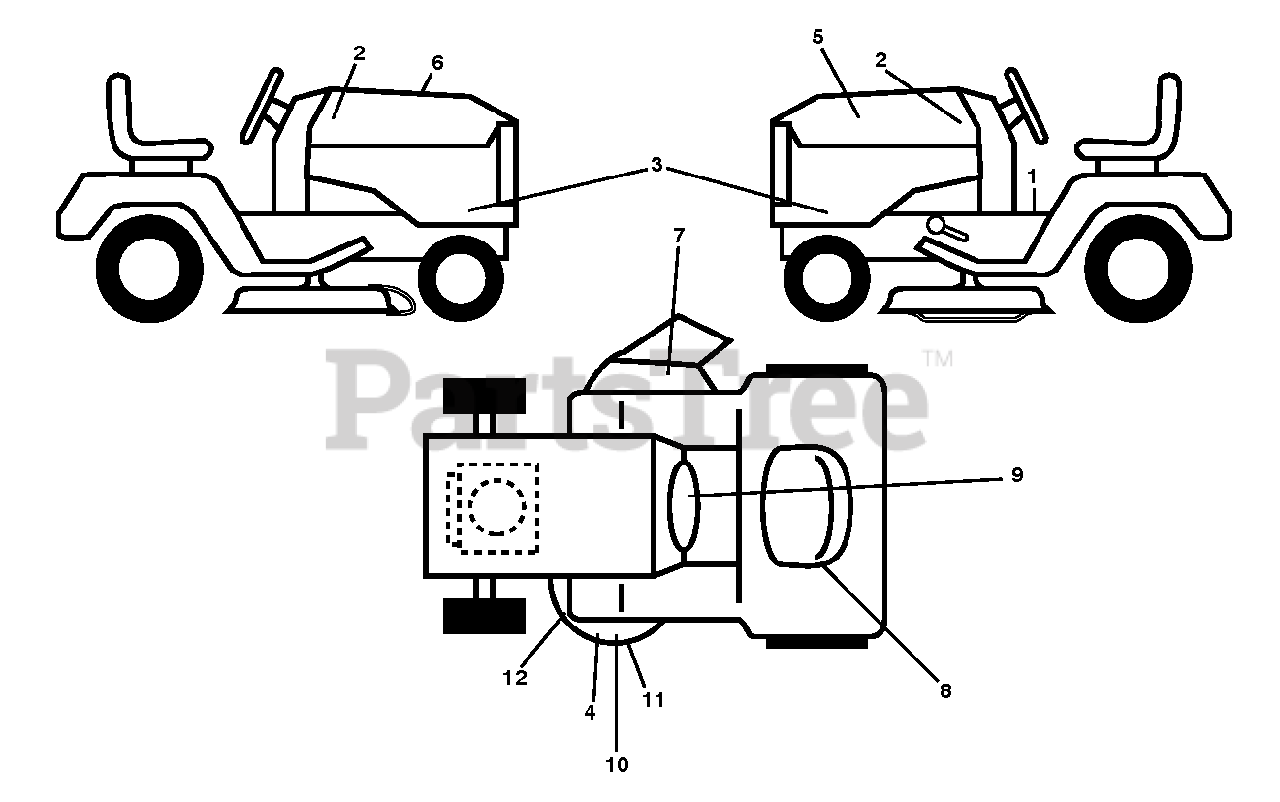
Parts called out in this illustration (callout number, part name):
1	DECAL.FENDER.WARNING.ENGLISH
2	DECAL.BADGE.170MM.TEXTLOGO.
3	DECAL.SDPNL.YT42DXLS.SET
4	DECAL.DECK.CLEARCUT.NOSTEP
5	DECAL.WARNING.CUST.RESP.E85.
6	DECAL.RPL.KH.KT7.TLB.42FCS.K46
7	DECAL.TRACT/ZTR.DECKWARN.HUSQ
8	DECAL.RESERVEFUELSELCTR.ENG
9	DECAL, WARNING SPARK ARRESTOR
10	Deck Decal, 42"
11	Deck Decal, WA
12	DECAL.V-BELT.SCH.42/46"MEC/ELE
